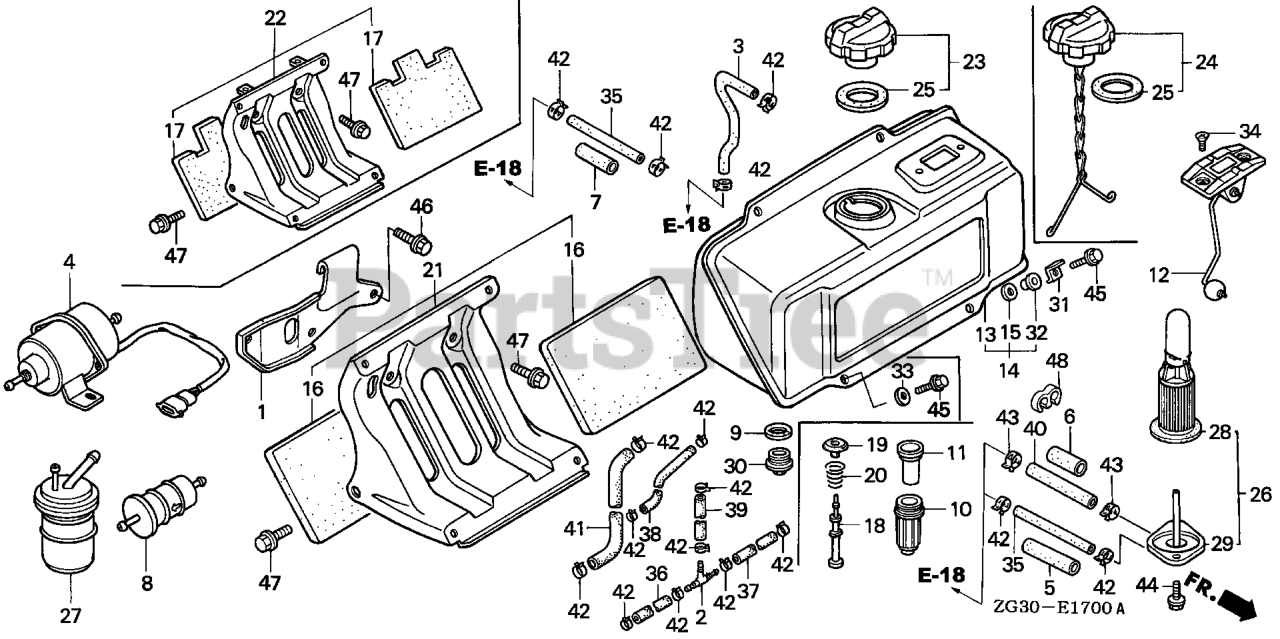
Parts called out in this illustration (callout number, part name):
1	HANGER, ENGINE
3	TUBE, FUEL
5	RUBBER, SUPPORTER (A)
6	RUBBER, SUPPORTER (B)
7	RUBBER, SUPPORTER (C)
9	GASKET
12	GAUGE ASSY., FUEL
13	TANK, FUEL *R280* (GAUGE) (POWER RED)
16	SEAT, TANK STAY
21	STAY, FUEL TANK
23	CAP, FUEL FILLER
25	GASKET, FUEL FILLER CAP (39X58X3) (NOT AVAILABLE)
25	GASKET, FUEL FILLER CAP Use from Engine SN 1543258.
25	GASKET, FUEL FILLER CAP (39X58X3)
26	FILTER ASSY., FUEL
28	STRAINER
29	BODY, STRAINER
30	BOLT, DRAIN
31	WASHER, SPECIAL (6MM)
34	SCREW, FLAT (5X10)
35	BULK HOSE, FUEL (4.5X3000) (Honda Code 5137104). (4.5X140)
40	BULK HOSE, FUEL (8X1000) (95001-80001-(95001-80001-60M)
42	CLIP, TUBE (D8)
43	CLIP, TUBE (D12.5)
44	BOLT, FLANGE (6X12) Use up to Engine SN 1543277.
45	BOLT, FLANGE (6X14)
47	BOLT, FLANGE (8X22) Use from Engine SN 1609607.
